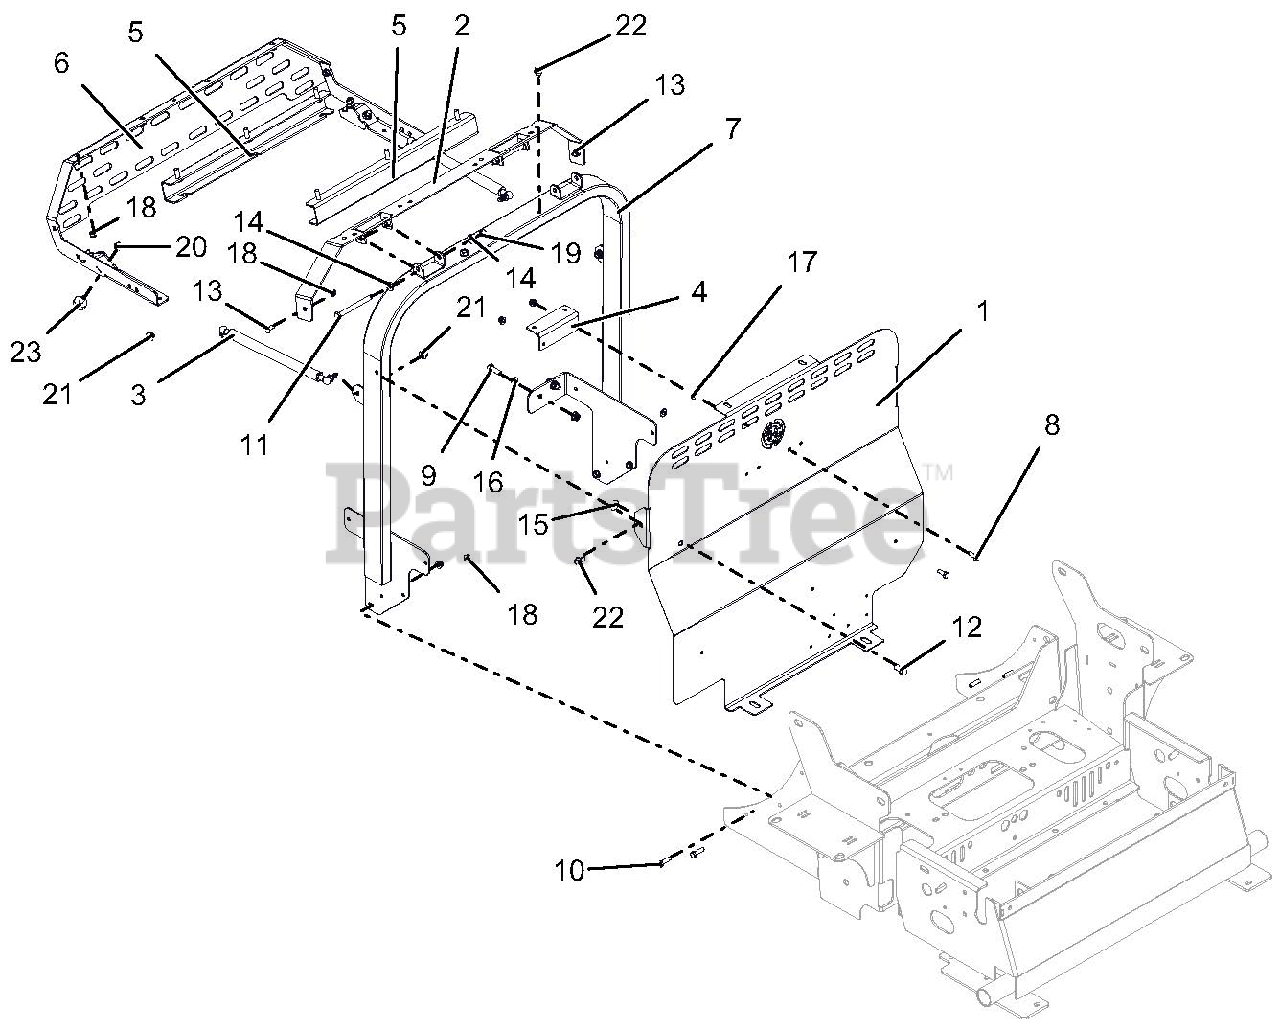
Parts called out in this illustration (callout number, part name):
1	GUARD, OPERATOR PT400 DIESEL
2	SUPPORT, DIESEL HOOD FRONT
3	STRT, GAS
4	BRKT, SIGNAL MOUNT - BLACK
5	WLDMT, DIESEL RADIATOR ISO CHANNEL
6	WLDMT, RADIATOR / HOOD SUPPORT REAR
7	WLDMT, RADIATOR /HOOD MOUNT
8	BLT-HEX .25-20X.75 GR5 YWZC
9	BLT-HEX .31-18X1.00 GR5 YWZC
10	BLT-HEX .25-20X1.00 GR5 YWZC
11	BLT-HEX .31-18X3.50 GR5 YWZC
12	BLT-HEX .38-16X.75 GR5 YWZC
13	BLT, RDHDSQNK .25-20 X .625 YWZC RED HEAD
14	WSHR-FL-NYL .375X.75X.060
15	WSHR-FL-STL.406X.812X.065 YWZ
16	WSHR-FL-STL.344X.688X.065YWZC
17	WSHR-FL-STL.281X.62X.065 YWZC
18	NUT-LK-NYL-FLG .25-20 YWZC
19	NUT-LK-CTR .31-18 YWZC
20	@NUT-SPNLK-FLG .312-18 YWZC
21	NUT-LK-NYL-FLG .31-18 YWZC
22	SCR-TAP .31-18X.50 HWH TR YWZ
23	BUMPER, RUBBER, 3/8" SILICON
